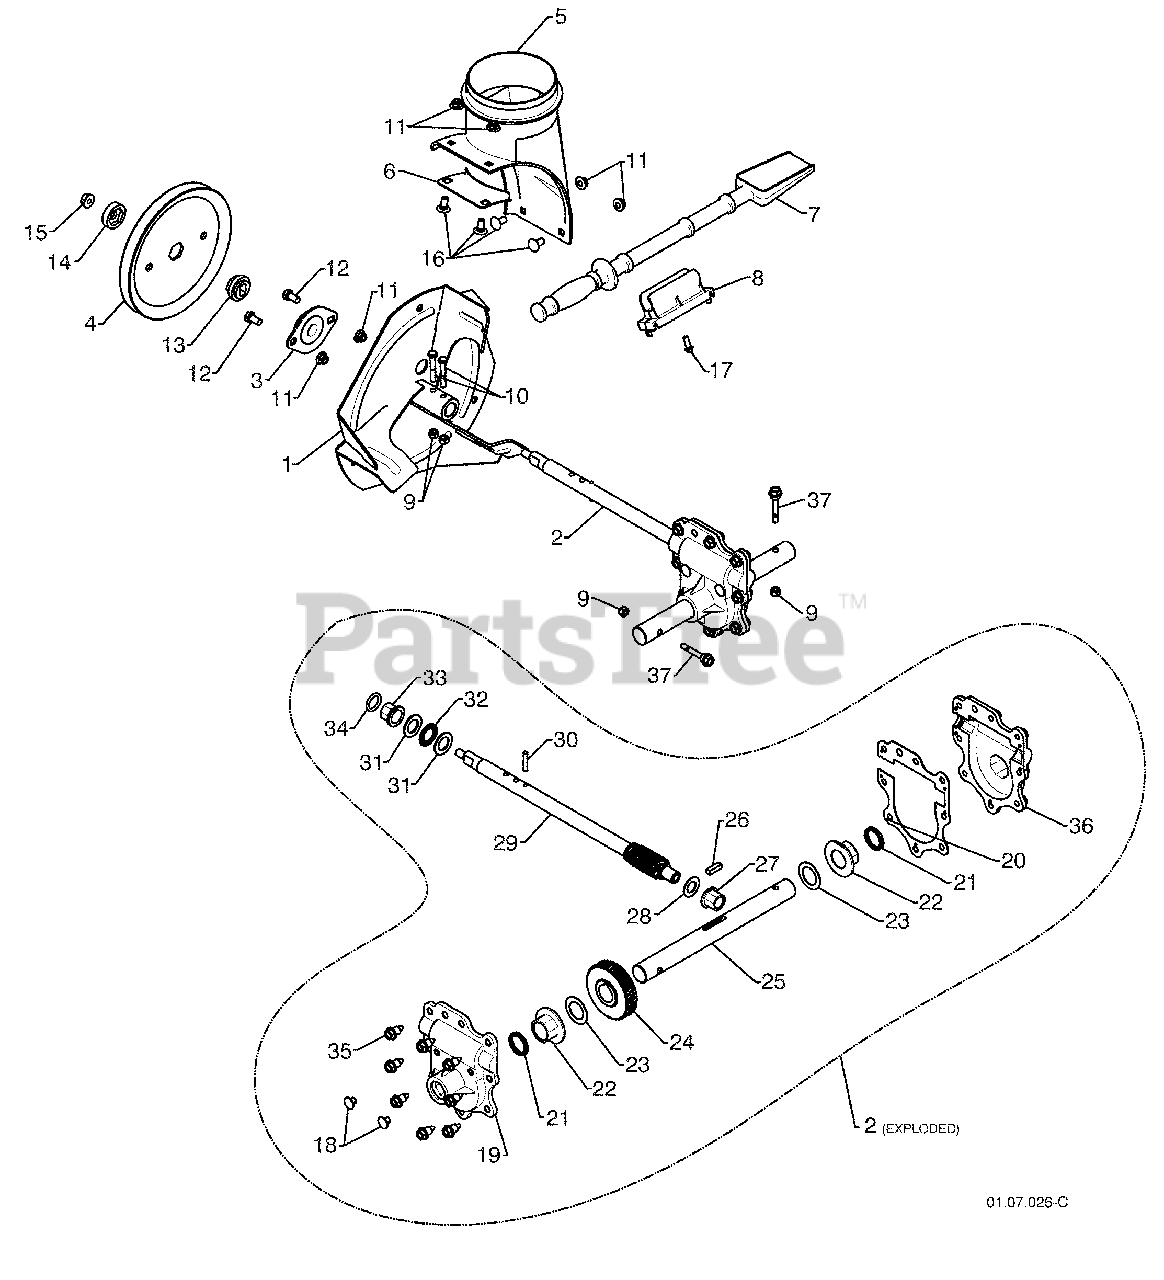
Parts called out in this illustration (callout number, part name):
1	IMPELLER
2	GEARBOX ASSEMBLY
4	IMPELLER PULLEY
5	DISCHARGE BASE
6	CORNER BRACKET
7	CLEAN OUT TOOL
9	NUT 1/4-20
10	SCREW 1/4-20 X .625
11	NUT 5/16-18
12	SCREW 5/16-18 X .625
13	IMPELLER HUB
14	IMPELLER SLEEVE
15	NUT 3/8-16
16	CARRIAGE BOLT
17	SCREW 13-16 X .625
18	PLUG
19	GEARBOX COVER RH
21	SEAL
22	BEARING
23	THRUST WASHER 1.00
24	WORM GEAR
25	AUGER SHAFT
26	SQUARE KEY
27	BEARING
28	THRUST WASHER
29	IMPELLER SHAFT
30	ROLL PIN
31	THRUST WASHER
32	THRUST BEARING
35	SCREW 5/16-18 X .750
36	GEARBOX COVER LH
37	SHEAR BOLTS
